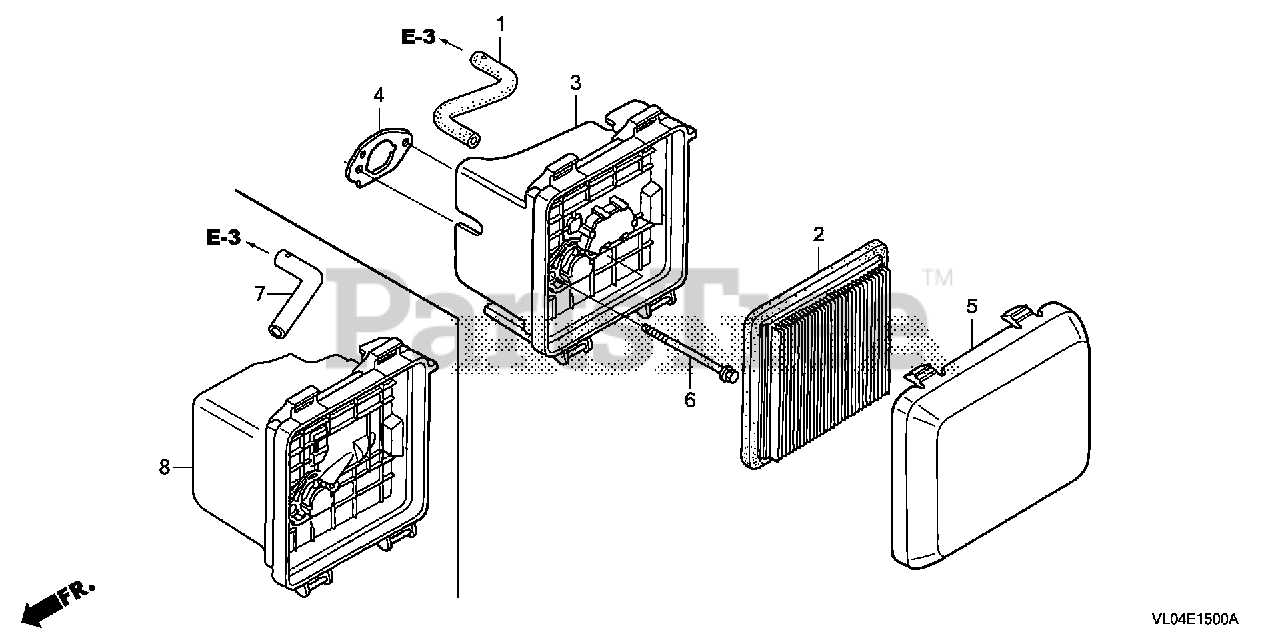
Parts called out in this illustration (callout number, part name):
1	TUBE, BREATHER
2	ELEMENT, AIR CLEANER (TOYO ROKI)
2	ELEMENT, AIR CLEANER (WIX FILTERS)
3	CASE ASSY., AIR CLEANER
4	GASKET, AIR CLEANER
5	COVER, AIR CLEANER
6	BOLT, SPECIAL (6MM)
